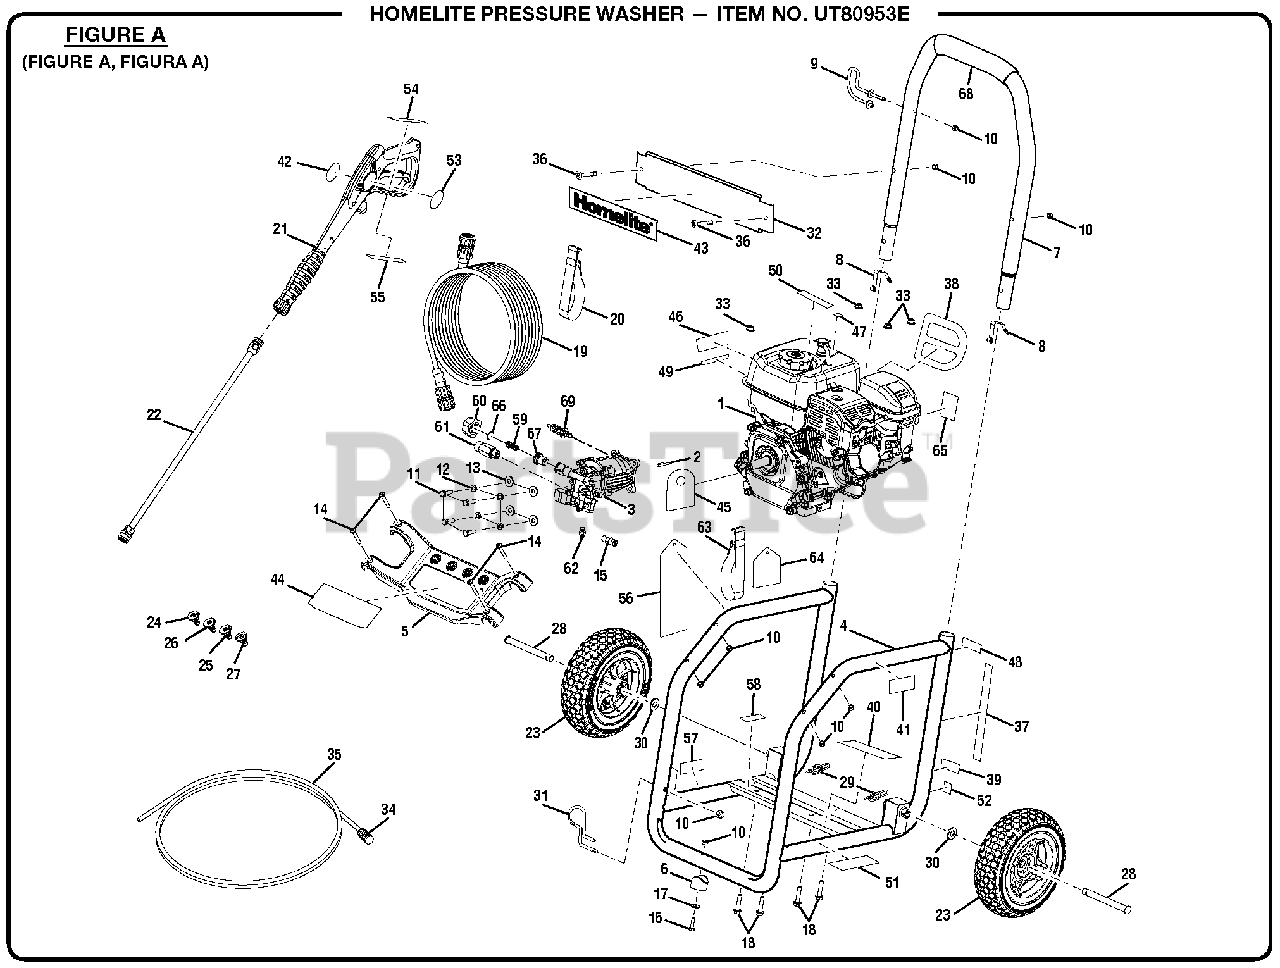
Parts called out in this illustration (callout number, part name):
1	Engine (RATO 180cc)
2	Output Shaft Key (3/16 x 40 mm)
4	Main Frame
5	Nozzle Holder
6	Rubber Foot
7	Handle Assembly
8	Lock Button w/Spring Clip
9	Wand Holder (Upper)
10	Lock Nut (1/4-20)
11	Bolt (5/16-24 x 27 mm, Hex Hd.)
12	Lock Washer (5/16 in.)
13	Washer (5/16 in.)
14	Screw (1/4-20 x 2.0 in., Torx)
15	Thermal Release Valve
16	Bolt (1/4-20 x 1-1/4 in.)
17	Washer (1/4 in.)
18	Bolt (M8 x 40 mm, Hex Flange Hd.)
20	Hook and Loop Strap
21	Trigger Handle
22	Spray Wand Assembly
23	Wheel Assembly (10 in. x 3 in.)
24	0deg Nozzle
25	40deg Nozzle
26	25deg Nozzle
27	Soap Nozzle
29	Hitch Pin
30	Washer (1/2 in.)
31	Wand Holder (Lower)
32	Front Panel
33	Lock Nut (M8 x 1.25)
35	Chemical Siphon Tube
36	Screw (1/4-20 x 1.57 in., Torx T-30)
37	Quick Start Label
38	Recoil Label
39	Choke Label
40	Data Label
41	Hot Surface Label
42	Trigger Handle Logo Label
43	Homelite Label
44	Performance Label
45	Add Oil Label
46	Danger Label
47	E85 Label
48	Homelite Inquiries Label
49	EMC Compliance Label
50	No Oil to Gas Label
51	Combustion Label
52	Fuel Label
53	Warning Label
54	Warning Label (French and Spanish)
55	Wand Label (Max Rating)
56	Danger Hangtag
57	Lubricant Label
58	Dip Stick Label
60	Inlet Adapter
61	Outlet Tube
62	Soap Injector Kit
63	Hook and Loop Strap
64	Nozzle Instructions Hangtag
65	Engine Label (On-Off)
67	Inlet Connector
68	Foam Grip
69	Unloader Valve Assembly
